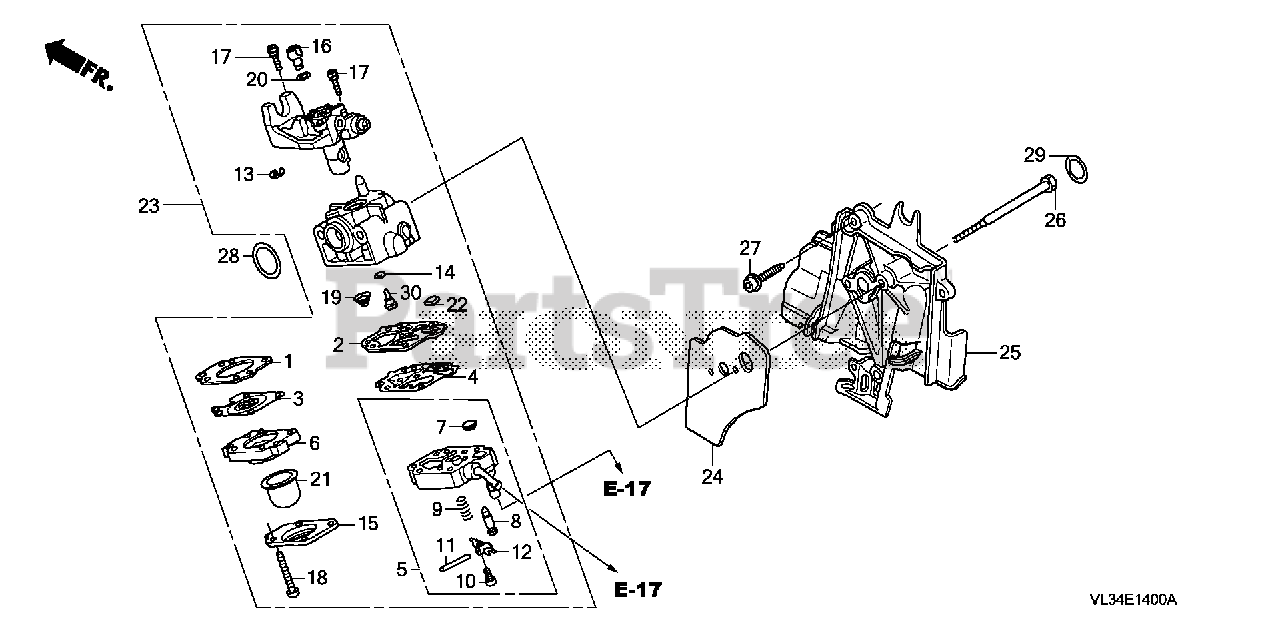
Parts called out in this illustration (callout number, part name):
1	GASKET, METERING DIAPHRAGM
2	GASKET, PUMP (CARBURETOR NO.)
3	DIAPHRAGM ASSY., METERING
4	DIAPHRAGM, PUMP
5	BODY ASSY., PUMP (CARBURETOR NO.)
6	BODY ASSY., AIR PURGE
7	SCREEN, INLET (CARBURETOR NO.)
8	VALVE, INLET NEEDLE
9	SPRING, METERING LEVER
10	SCREW, METERING LEVER PIN
11	PIN, METERING LEVER
12	LEVER, METERING
13	RING, RETAINING
15	COVER, PRIMER PUMP
17	SCREW, THROTTLE COLLAR
18	SCREW, PUMP COVER
19	SPRING, PUMP
21	PUMP, PRIMER
22	FILTER, FUEL INLET (CARBURETOR NO.)
23	CARBURETOR ASSY. (WYB 16C)
23	CARBURETOR ASSY. (WYB 14D)
23	CARBURETOR ASSY. (WYB 34A/B)
23	CARBURETOR ASSY. (WYB 36A/B)
24	GASKET, CARBURETOR
25	SHROUD
26	BOLT (5X53)
27	BOLT, SOCKET (5X16)
28	O-RING (14.8X2.4)
29	O-RING (12.3X2.4) (CARBURETOR NO.)
30	JET (#33) (CARBURETOR NO.)
30	JET (#34) (CARBURETOR NO.)
30	JET (#35) (CARBURETOR NO.)
30	JET (#32) (CARBURETOR NO.)
30	JET (#36) (CARBURETOR NO.)
30	JET (#37) (CARBURETOR NO.)
